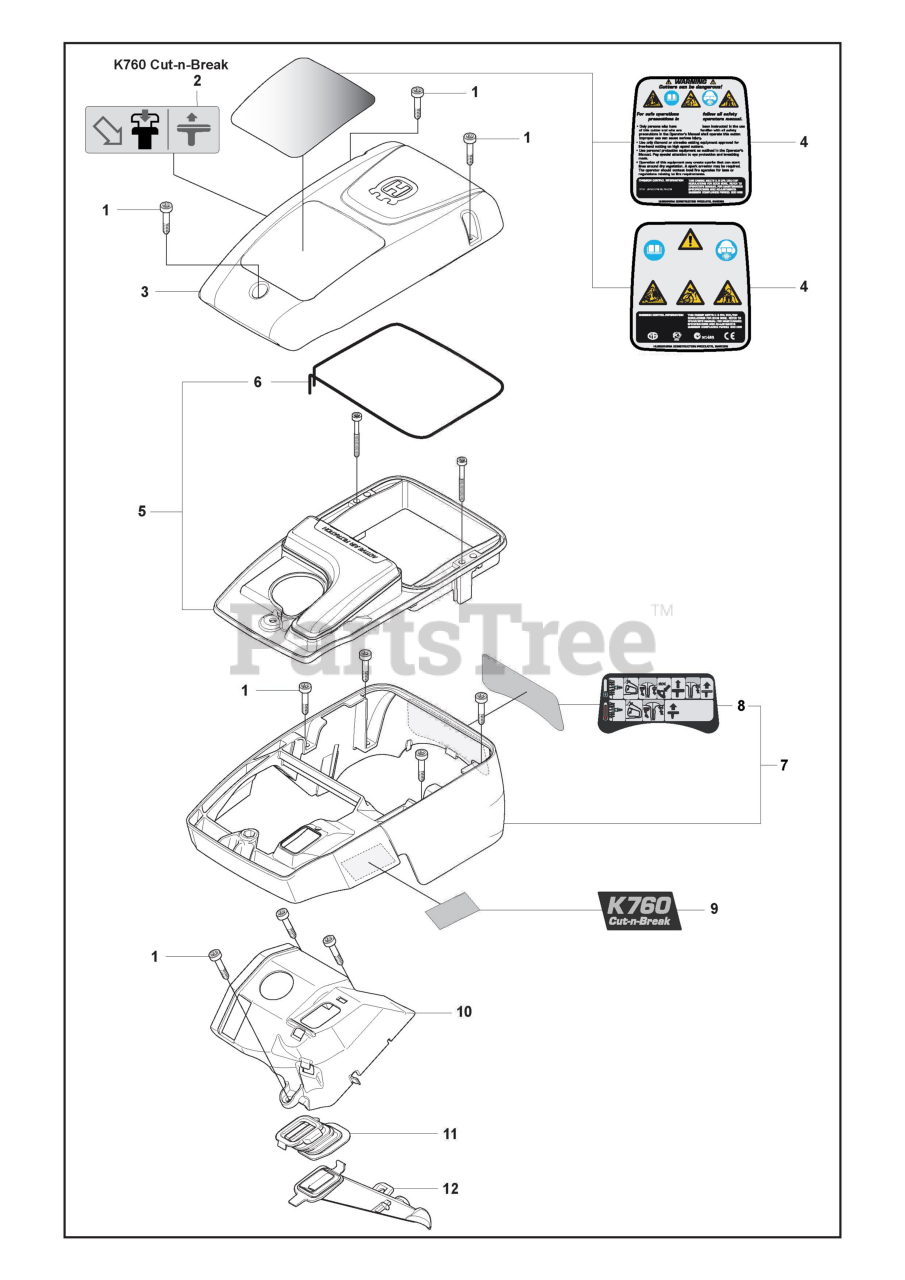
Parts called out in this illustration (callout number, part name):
3	Filter Cover
4	Decal
5	Filter Holder Assy
6	Sealing
7	Cylinder Cover Assy
9	Decal
10	Cover
11	Bellows
12	Air Nozzle
